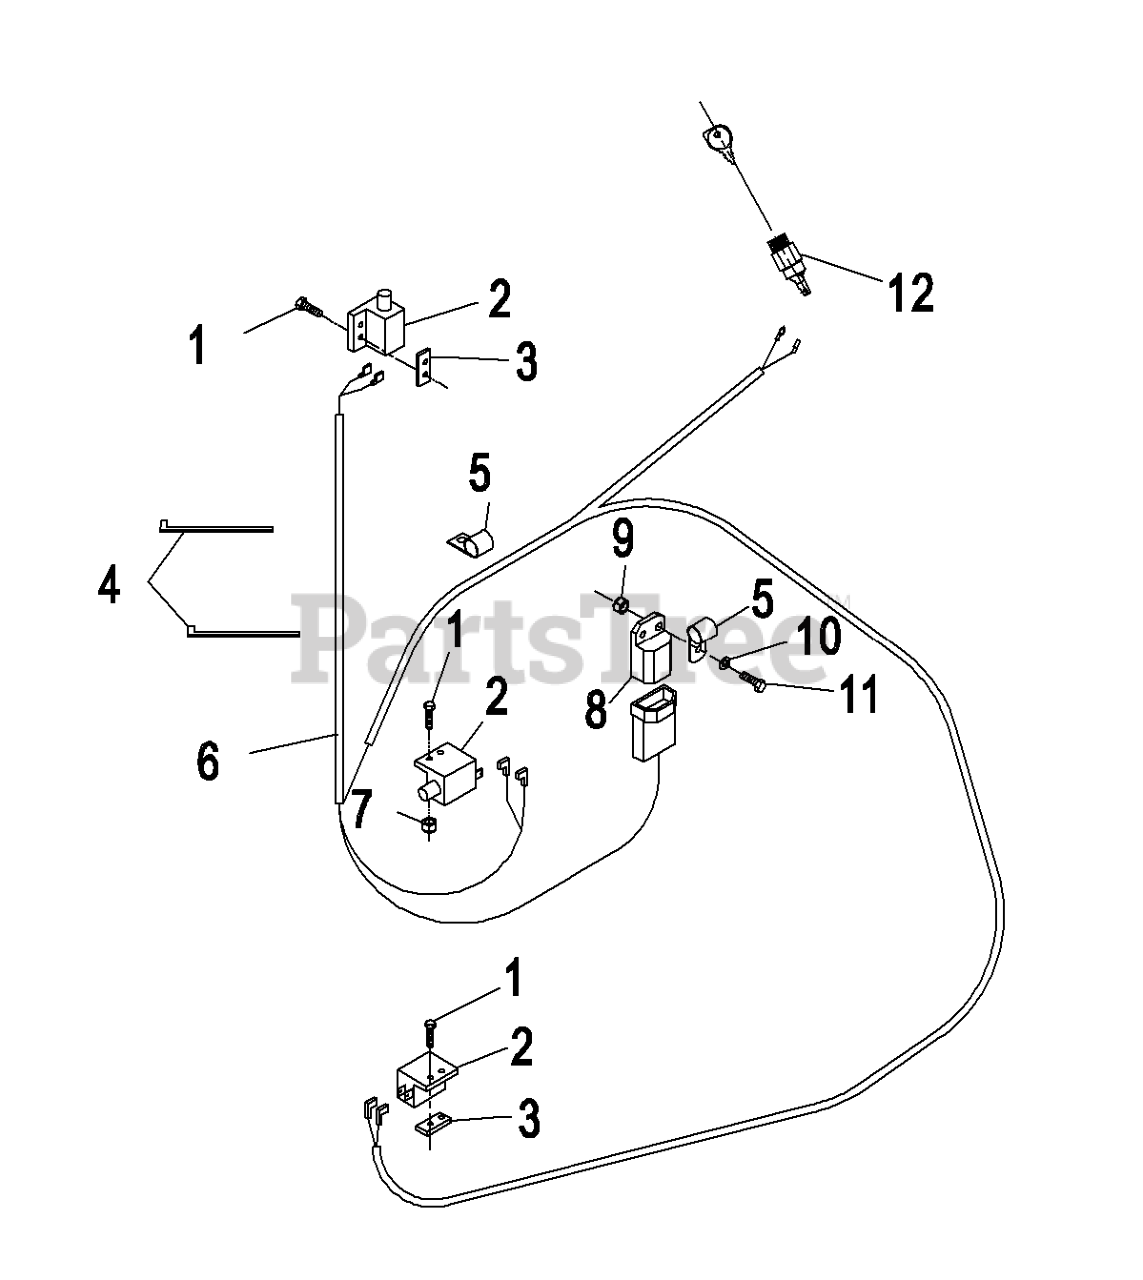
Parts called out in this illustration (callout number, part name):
1	SCREW-PPH
2	SWITCH-OPEN, NORMALLY
3	PLATE-TAPPED
4	TIE-CABLE
5	CLIP-LOOM
6	HARNESS,WIRING KA PULL ST
7	NUT-SQH
8	MODULE-INTERLOCK
9	NUT-LOCK, NI
10	WASHER-FLAT
11	SCREW-HH
12	SWITCH & KEY (INCLUDES NU
